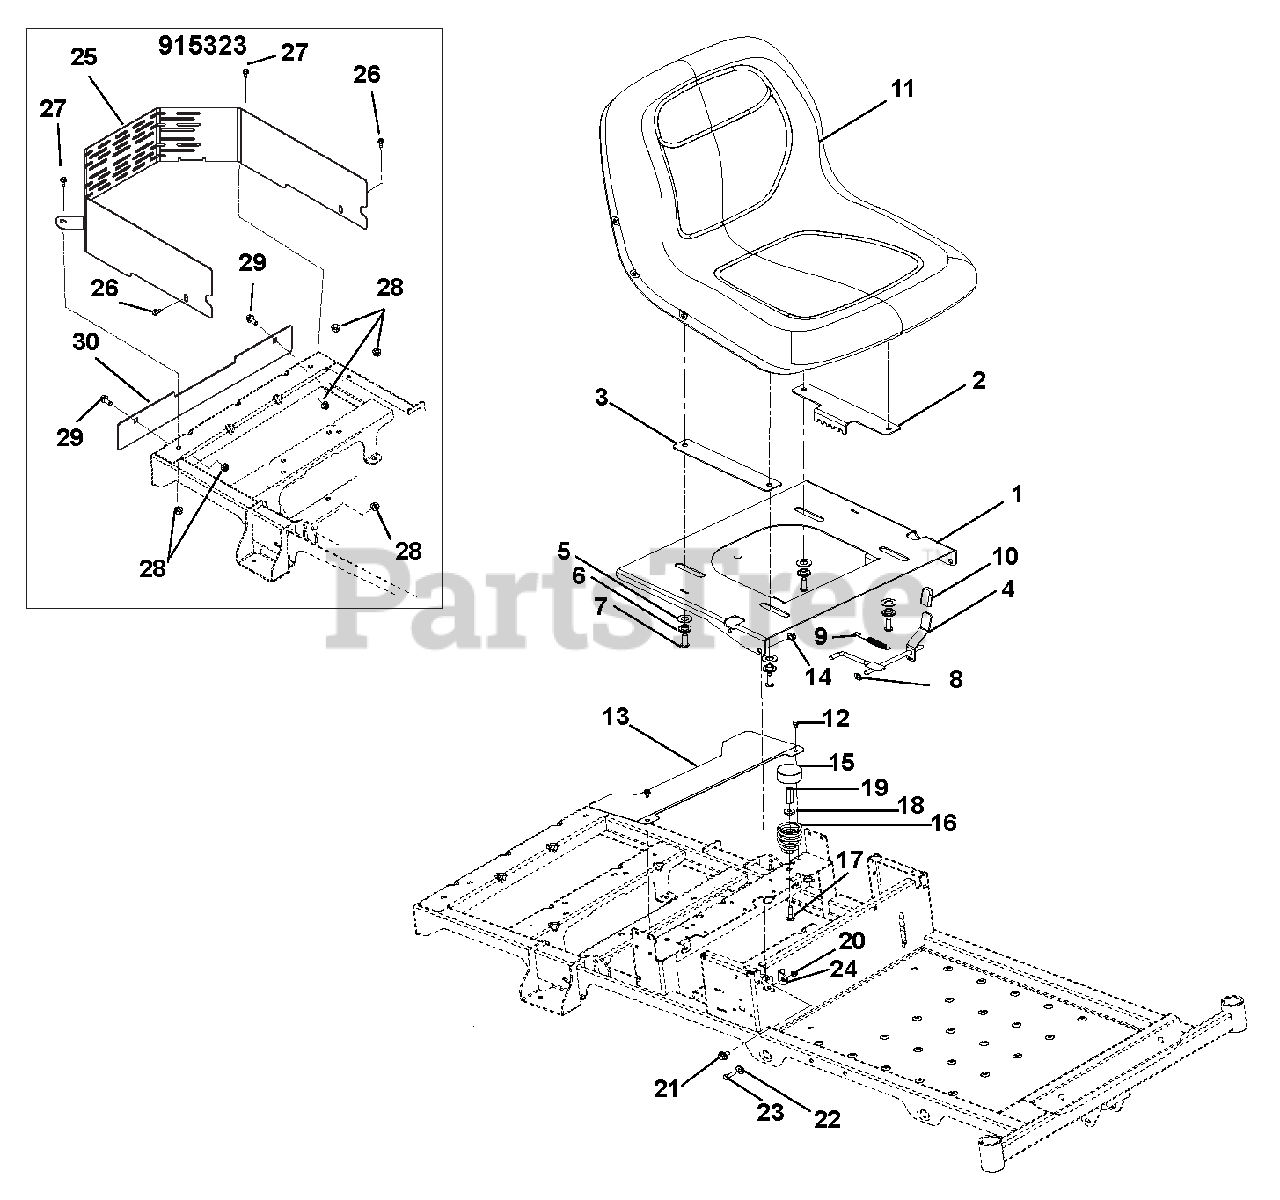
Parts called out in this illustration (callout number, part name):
1	PLATE, SEAT, ADJUSTABLE
2	PLATE, ADJUSTABLE SEAT TRACK
3	PLATE, ADJUSTABLE SEAT SLIDE
4	WLDMT, ADJUSTABLE SEAT LATCH
5	WSHR-FL-STL .505X1.00X.062YWZC
6	BSHG-FLG .32X.500X.344X.880
7	SCR-SKH .31-18X1.0 BTNHD YWZC
8	NUT-PUSH .312
9	SG-TENS .043X.44X3.31 WLD 5.8
10	GRIP, SEAT LEVER, GREY
11	SEAT, MILSCO XB180 GRAY
12	@SCR-TAP .25-20X.50 HWH TR YWZ
13	GUARD, FAN
14	@NUT-LK-TOP-FLG .38-16 YWZC
15	HUB CAP
16	SPRING, SEAT
17	@BLT-RDHDSQNK .31-18X1.50 G5YZ
18	WSHR-FL-STL .328X.87X.179 YWZC
19	NUT, COUPLING 5/16-18 X 1 3/4
20	@NUT-LK-NYL-FLG .31-18 YWZC
21	BOLT-SHLDR .375-16X.150
22	BSHG, FLG .325X.499X.26X.88
23	@BLT-HEX .31-18X1.00 GR5 YWZC
24	BRKT, SEAT STOP
25	WALL, CE REACH-IN (ZOOM)
26	@BLT-HEX .38-16X.75 GR5 YWZC
27	@BLT-HEX .38-16X1.00 GR5 YWZC
28	NUT-LK-CTR-FLG .38-16 YWZC
29	@BLT-RDHDSQNK .38-16X.75 G5YZ
30	FLANGE, ZOOM MUFFLER (CE)
